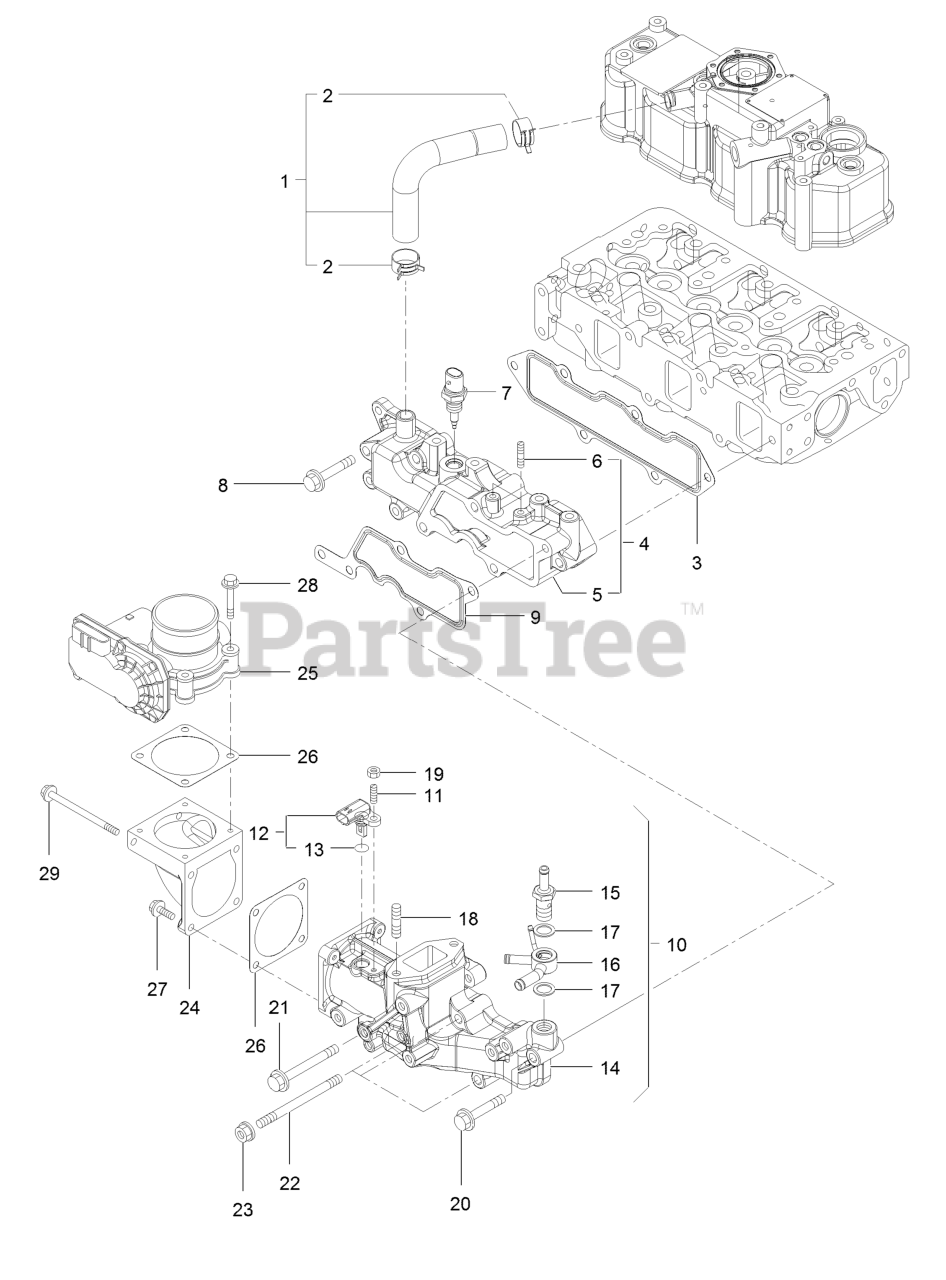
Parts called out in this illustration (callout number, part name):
2	Clip-Hose
3	Gasket-Manifold, Intake
4	Intake Manifold ASM
5	Manifold-Intake
7	Sensor-Temp, Air
9	Gasket-Collector
10	Intake Collector ASM
12	Sensor-Temp, Air
13	O Ring-Sensor, Temp
14	Collector-Intake
15	Joint-Hose
16	Joint-Hose
17	Washer-Seal
24	Bend-Inlet
25	Body-Throttle
26	Gasket-Throttle
